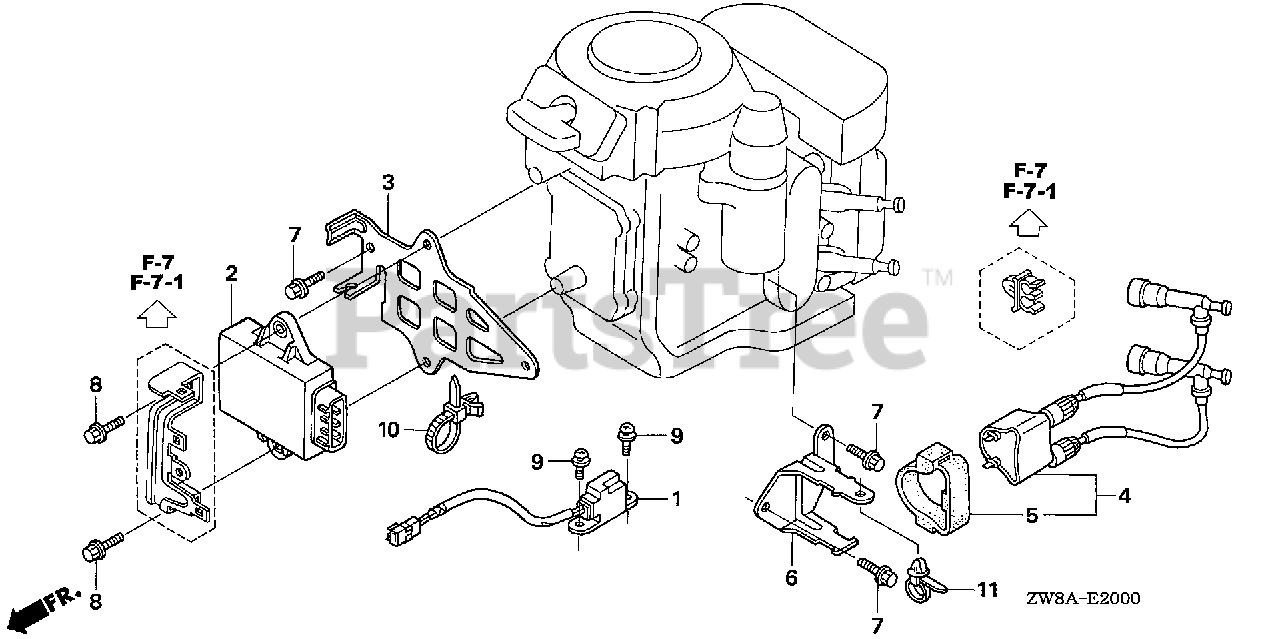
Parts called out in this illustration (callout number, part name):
1	COIL ASSY., PULSER
2	MODULE, IGNITION CONTROL (CDI)
3	PLATE, C.D.I.
4	COIL ASSY., IGNITION
5	SUSPENSION, IGNITION COIL
6	BRACKET, IGNITION COIL
7	BOLT, FLANGE (6X14) (CT200)
8	BOLT, FLANGE (6X25)
9	SCREW-WASHER (5X16)
10	STRAP, CABLE (118MM) (BLACK)
11	CLIP, HARNESS BAND (151.5MM) (NATURAL)
